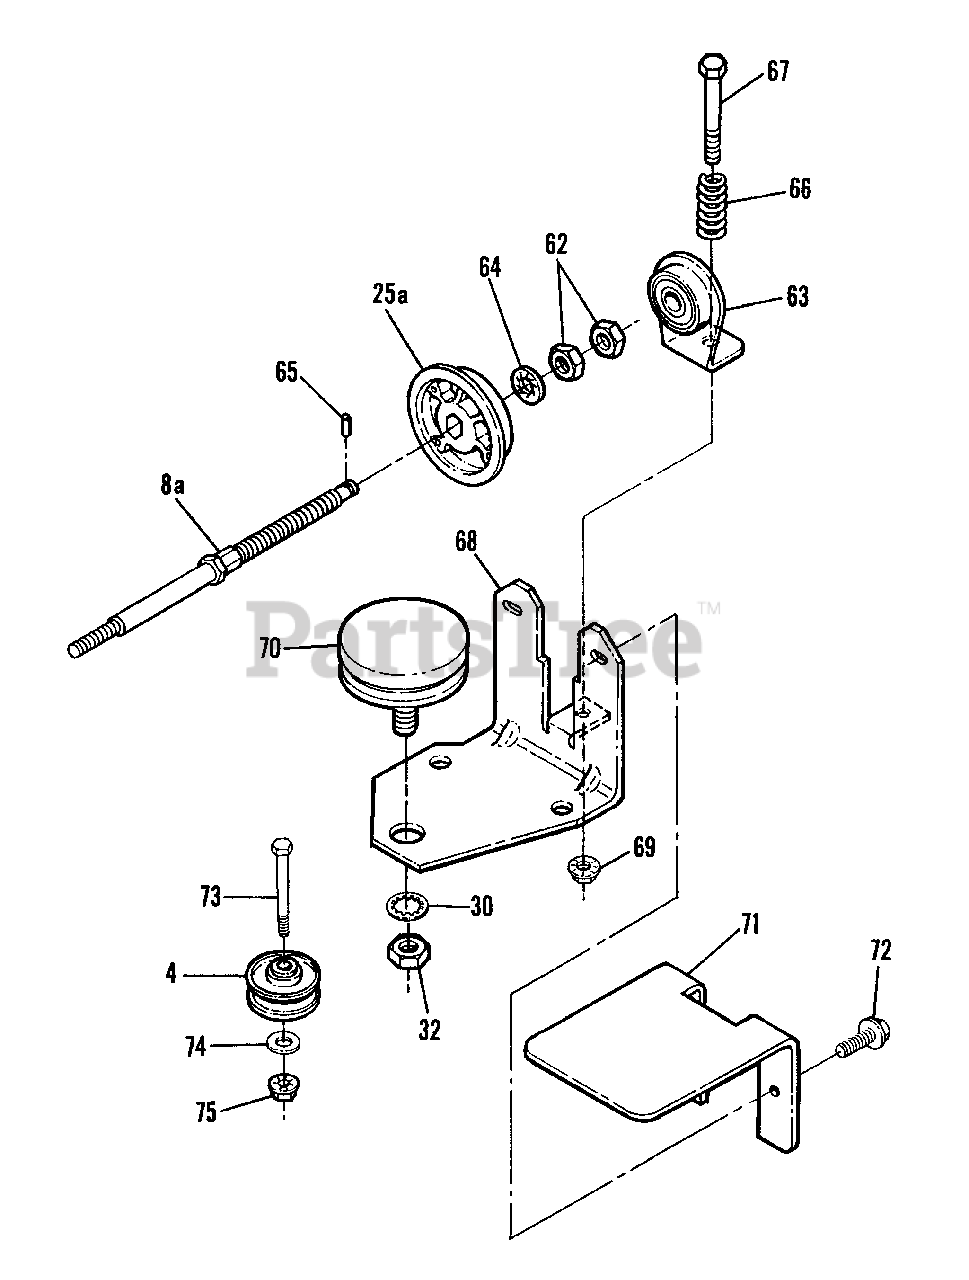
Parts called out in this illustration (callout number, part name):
4	PULLEY, Idler
8A	*SHAFT, Drive
25A	*HUB, Driven Disc
30	GUIDE, Thrust Plate
32	NUT, 3/8-24 Hex, Grade 2
62	*NUT, 1/2-20 Hex, Grade 2
63	*ASSEMBLY, Holder & Bearing
64	*WASHER, 1/2" Internal Tooth Lock
65	*PIN, 1/8 x 3/4" Roll
66	*SPRING
67	*SCREW, 5/16-24 x 2-3/4" Hex Head Cap, Grade 5
68	*BRACKET, Deck
69	*NUT, 5/16-24 Hex Flange Lock
70	*ASSEMBLY, Drive Disc
71	*COVER, Driven Ring
72	*SCREW, #10-24 x 1/2" Hex Washer Self-Tap (Torx)
73	*SCREW, 1/4-20 x 1-1/2" Hex Head Cap, Grade 5
74	*WASHER, 13/32 x 3/4"
75	*NUT, 1/4-20 Hex Flange Lock
